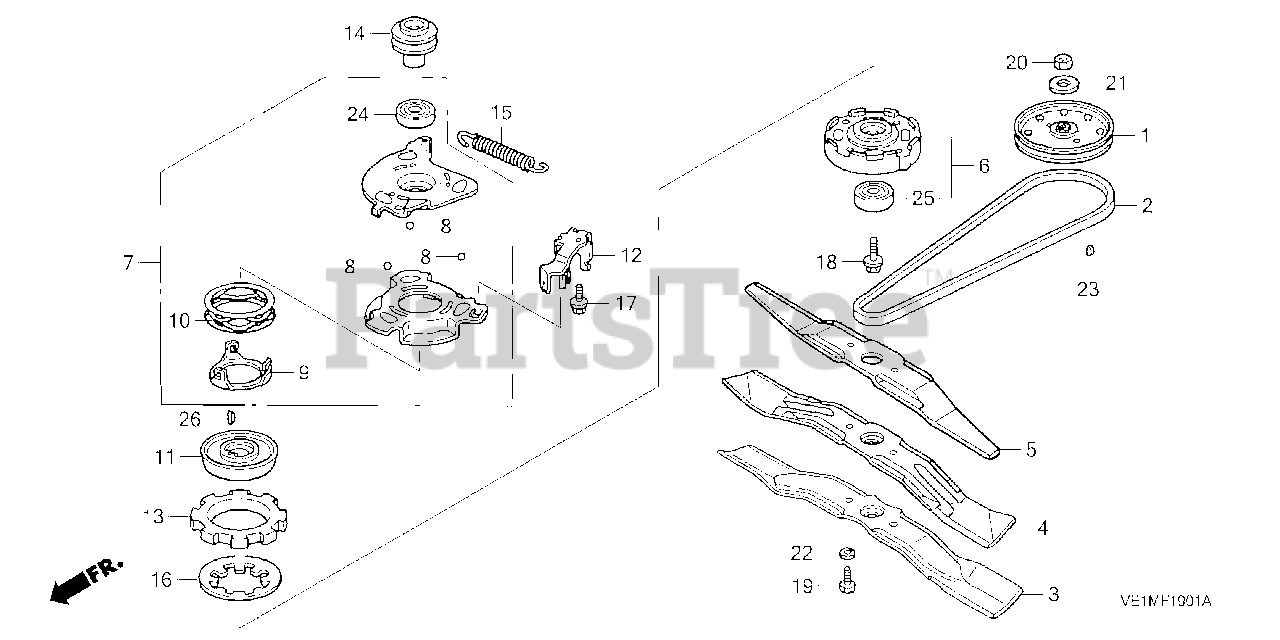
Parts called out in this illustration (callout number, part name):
2	V-BELT (3L-36.3)
3	BLADE, ROTARY MULCHING (LOWER)
4	BLADE, MULCHING
4	BLADE, ROTARY (PCD=88MM)
5	BLADE, ROTARY (UPPER) (PCD=88MM)
6	HOLDER ASSY., BLADE
7	PLATE ASSY., BALL CONTROL
8	BALL, STEEL
9	PLATE, SPRING HOOK
10	SPRING, BALL PLATE
11	DISK, DRIVE
12	HOOK, RETURN SPRING
13	DISK, DRIVEN
14	PULLEY, DRIVE
15	SPRING, CLUTCH RETURN
15	SPRING ASSY., CLUTCH RETURN
16	SPRING, CLUTCH
17	BOLT, FLANGE (6X14) (CT200)
18	BOLT, FLANGE (10X24)
19	BOLT, HEX. (10X20)
22	WASHER, SPRING (10MM)
24	BEARING, RADIAL BALL (6006) (SST)
25	BEARING, RADIAL BALL (6204)
26	KEY, WOODRUFF (16X15)
